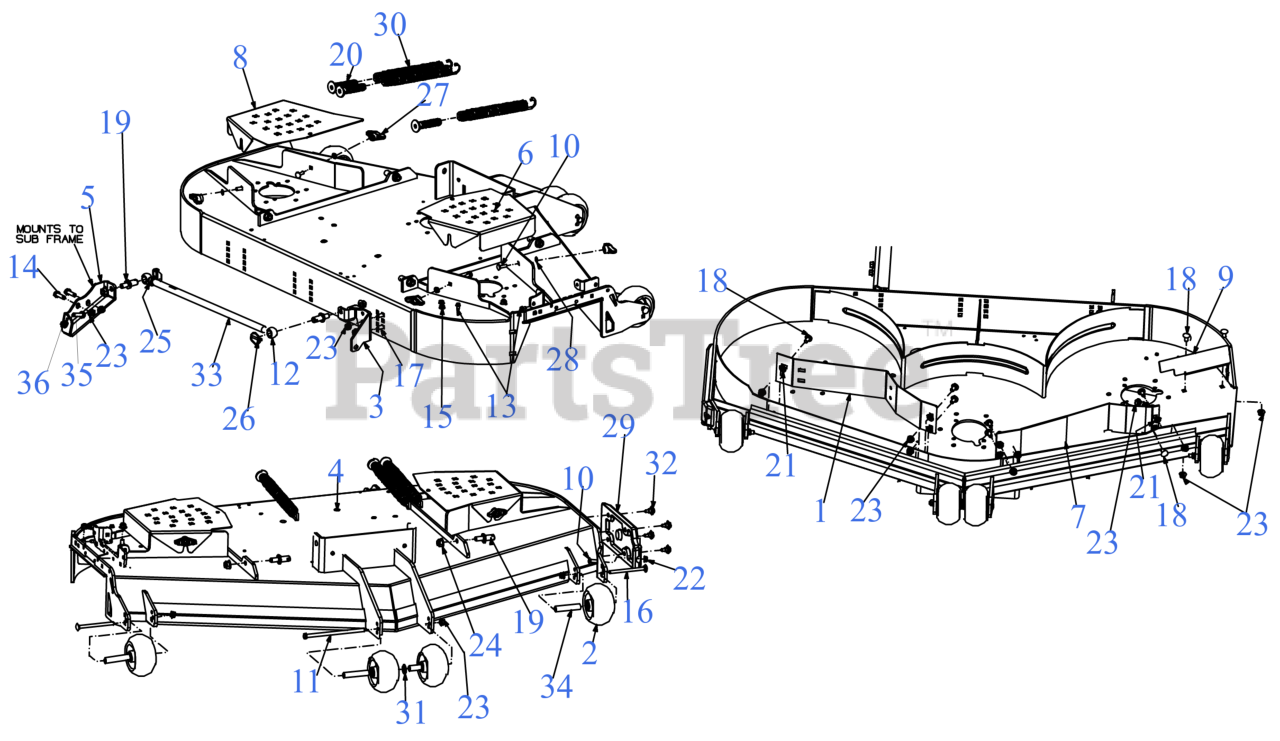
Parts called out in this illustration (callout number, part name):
1	BAFFLE - 60" ADJ
2	5" DIA DECK WHEEL COMPLETE
2	WHEEL BUSHING
5	STABILIZER MOUNTING BRACKET
10	CARRIAGE BOLT 5/16-18 x 1.00
11	SCREW 3/8-16 x 7.25 GR5
12	BOLT 5/8-16 x 2.63
13	SCREW 1/4-20 X.500
14	SCREW 3/8-16 x 1.25 GR5
15	SCREW 5/16-18 x .500
16	CARRIAGE BOLT 3/8-16 x 4.25 GR5
17	CARRIAGE BOLT 3/8-16 x 1.00 GR5
18	CARRIAGE BOLT 3/8-16 x .75
20	SPRING INSERT SCREW
22	FLANGE LOCK NUT 5/16-18
25	HEX JAM NUT
26	LYNCH PIN .1875
27	WING KNOB 5/16-18
29	DECK SKID PLATE (LH)
30	EXTENTION SPRING 1.20 x 11.35
31	FLAT WASHER .632X1.00X.16
32	SHOULDER SCREW .43X.29X5/16-18 TT
34	WHEEL SPACER .38ID x 3.04LG
35	HEX HEAD BOLT (3/8-16:1.50 GR8)
36	LOCK NUT (3/8-16)
